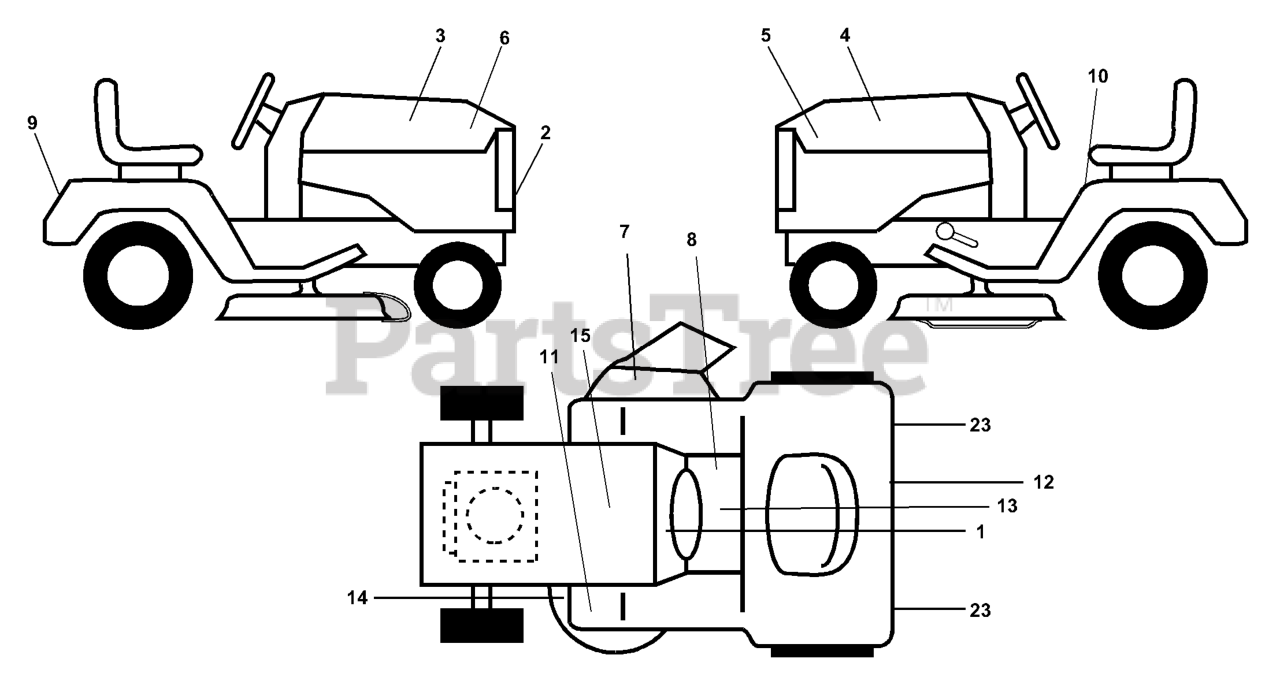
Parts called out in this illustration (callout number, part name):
2	DECAL GRILL HUSQ NLA
3	DECAL-HOOD R.H.
4	DECAL-HOOD L.H.
5	DECAL HOOD LH
6	DECAL HOOD RH
7	DECAL WARNING (ENGLISH/FRENCH)
8	DECAL PARK BRAKE
9	DECAL FENDER NLA
10	DECAL CAUTION
12	DECAL D-BAR
15	DECAL BTRY SYMBOLS
23	REFLECTOR-TAIL YT
